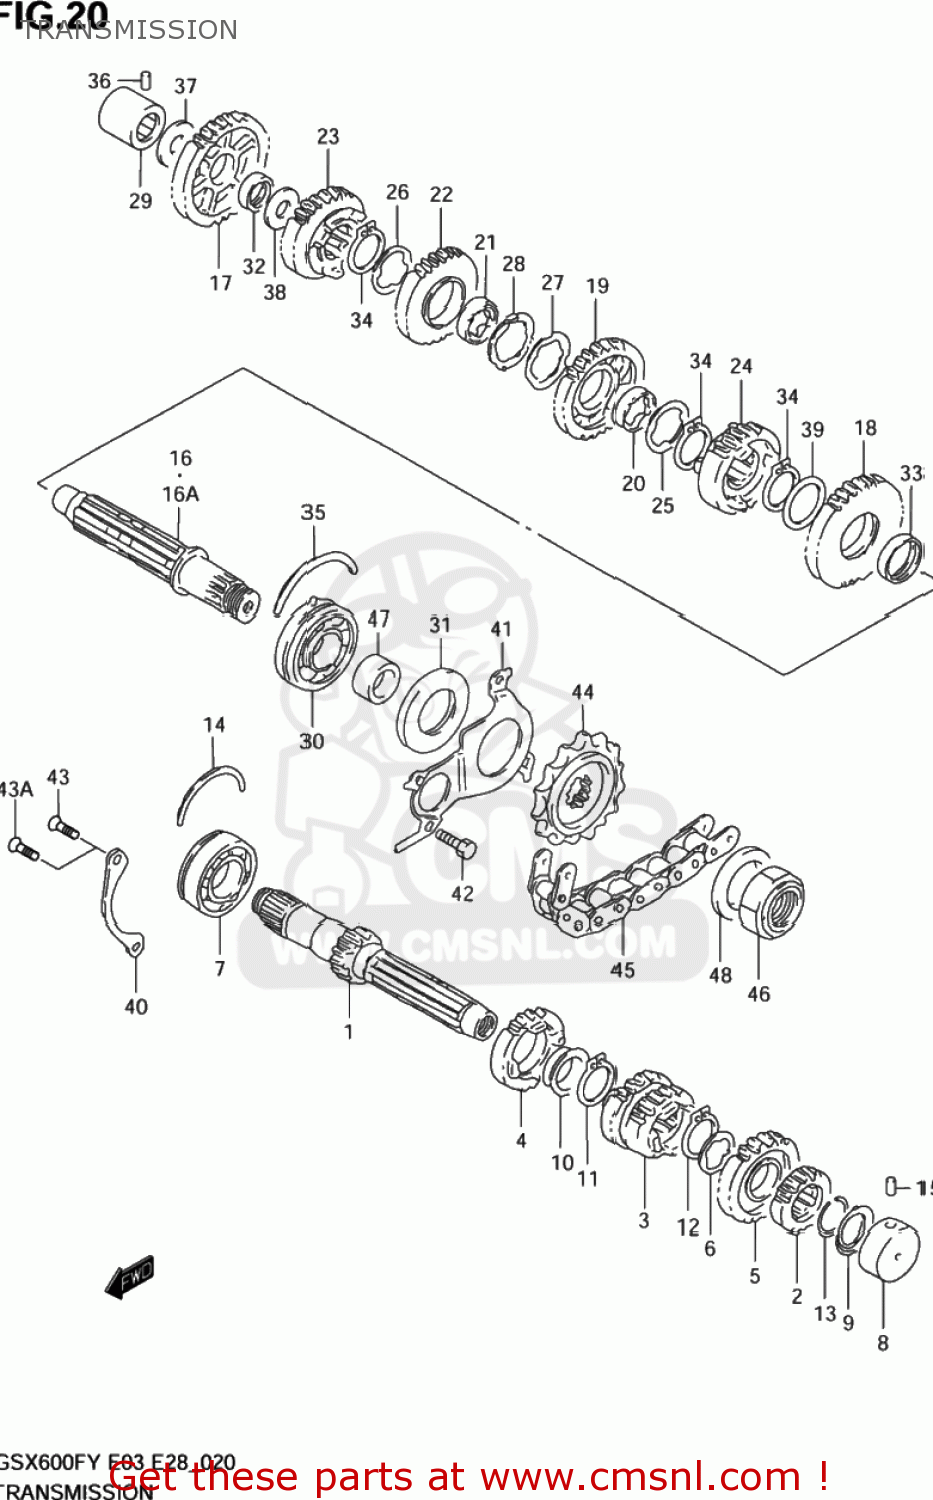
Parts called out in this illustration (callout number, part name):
1	SHAFT,COUNTER(NT:12)
2	GEAR,2ND DRIVE(NT:16)
3	GEAR,3RD & 4TH DRIVE(NT:17/20)
4	GEAR,5TH DRIVE(NT:22)
5	GEAR,6TH DRIVE(NT:21)
6	WASHER,LOCK
7	BEARING(25X62X17)
8	BEARING(20X34X17.5)
9	SEAL,OIL(20X31.2X2.7)
10	BUSHING
11	RING,SNAP
12	RING,SNAP
13	CIRCLIP
14	C RING
15	PIN
16	SHAFT,DRIVE
16A	SHAFT,DRIVE
17	GEAR,1ST DRIVEN(NT:37)
18	GEAR,2ND DRIVEN(NT:33)
19	GEAR,3RD DRIVEN(NT:28)
20	BUSH
21	BUSH
22	GEAR,4TH DRIVEN(NT:28)
23	GEAR,5TH DRIVEN(NT:27)
24	GEAR,6TH DRIVEN(NT:23)
25	WASHER,LOCK
26	WASHER,LOCK
27	WASHER,LOCK
28	WASHER
29	BEARING(20X34X20)
30	BEARING(25X62X21.6)
31	SEAL,OIL(34X62X6)
32	BUSH(22X26X9)
33	BUSH(28X32X9.5)
34	CIRCLIP
35	C RING
36	PIN
37	SHIM(20X34X1)
38	SHIM(22X34X1)
39	SHIM(28X38X1)
40	RETAINER,CNTR SHAFT BEARING
41	RETAINER,DRIVE SHAFT OIL SEAL
42	BOLT
43	SCREW
43A	SCREW(6X12)
44	SPROCKET,ENGINE(NT:15)
45	CHAIN ASSEMBLY,DRIVE 118LE
46	NUT
47	SPACER(25X34X17.5)
48	SHIM(25X40X1.5)
